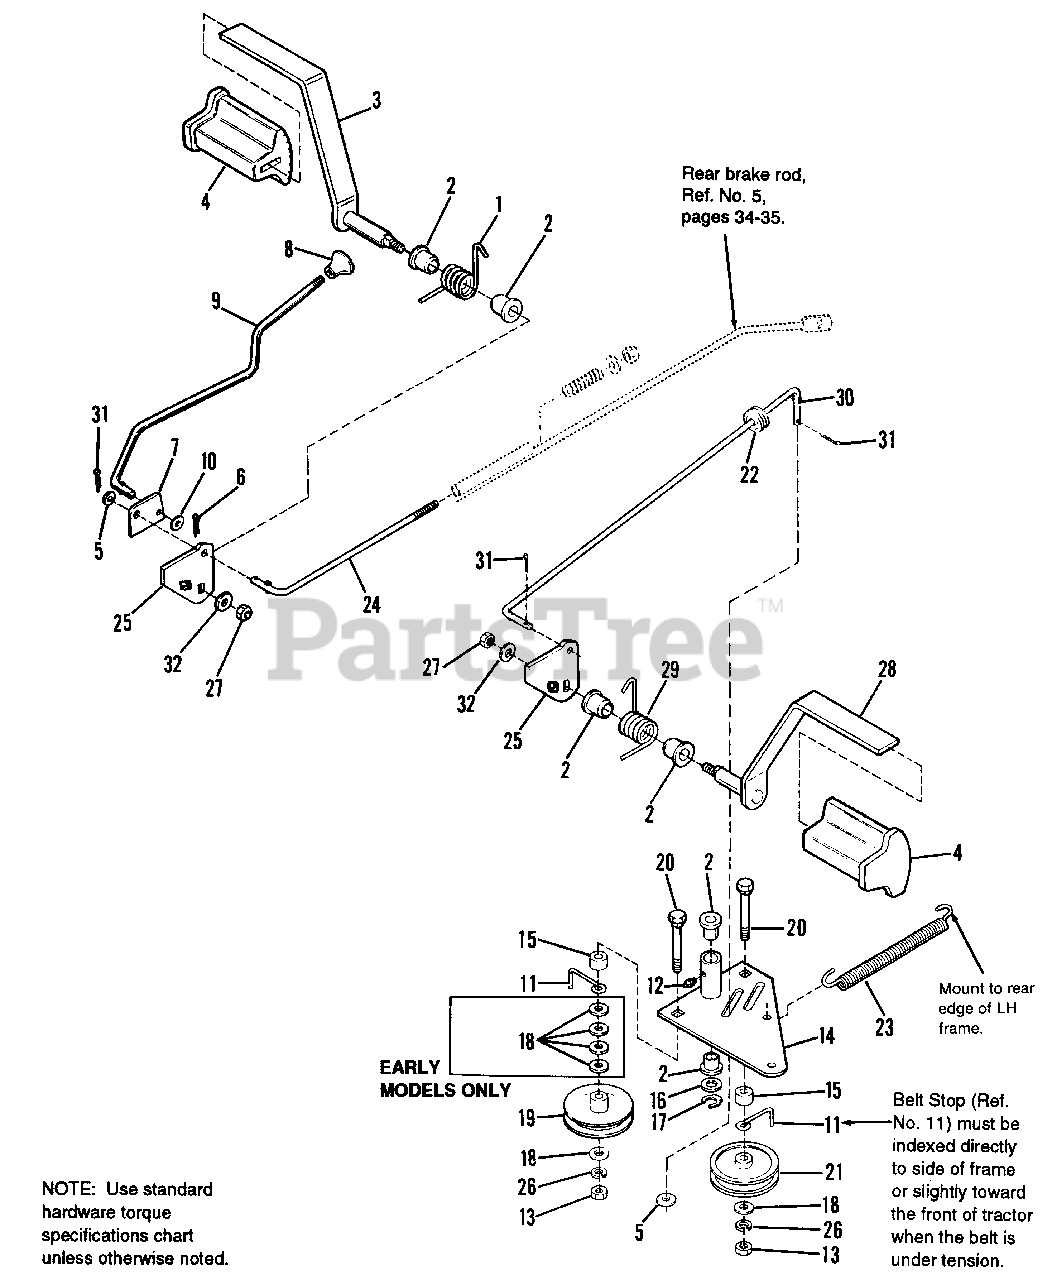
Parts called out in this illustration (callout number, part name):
1	SPRING, Torsion, R.H.
3	BRAKE PEDAL ASSY., R.H.
4	PAD, Foot Pedal
5	WASHER, Plain, 11/32
6	COTTER PIN
7	CAM, Parking Brake
8	KNOB, Plastic (Mfg. Nos. 1692024, 1692033, 1692301, 1692303)
8	KNOB, Soft (Mfg. Nos. 1692438, 1692444)
9	ROD, Parking Brake
10	WASHER, Plain, 1/4
12	FITTING, Grease
13	NUT, Hex, Full, 3/8-16
14	ARM ASSY., Idler
16	WASHER, 5/8
17	KLIPRING, 5/8
18	WASHER, Plain, 13/32 (Qty. 6 on early models only)
19	PULLEY, Flat, Idler
20	CAPSCREW, Hex, 3/8-16 x 2-3/4
21	PULLEY, "V"
23	SPRING, Drive
24	ROD, Brake, Front
25	ARM, Foot Pedal
26	LOCKWASHER, 3/8
27	NUT, Hex, Lock, 3/8-16
28	BRAKE PEDAL ASSY., L.H.
29	SPRING, Torsion, L.H.
30	ROD, Clutch
31	PIN, Cotter
32	WASHER
